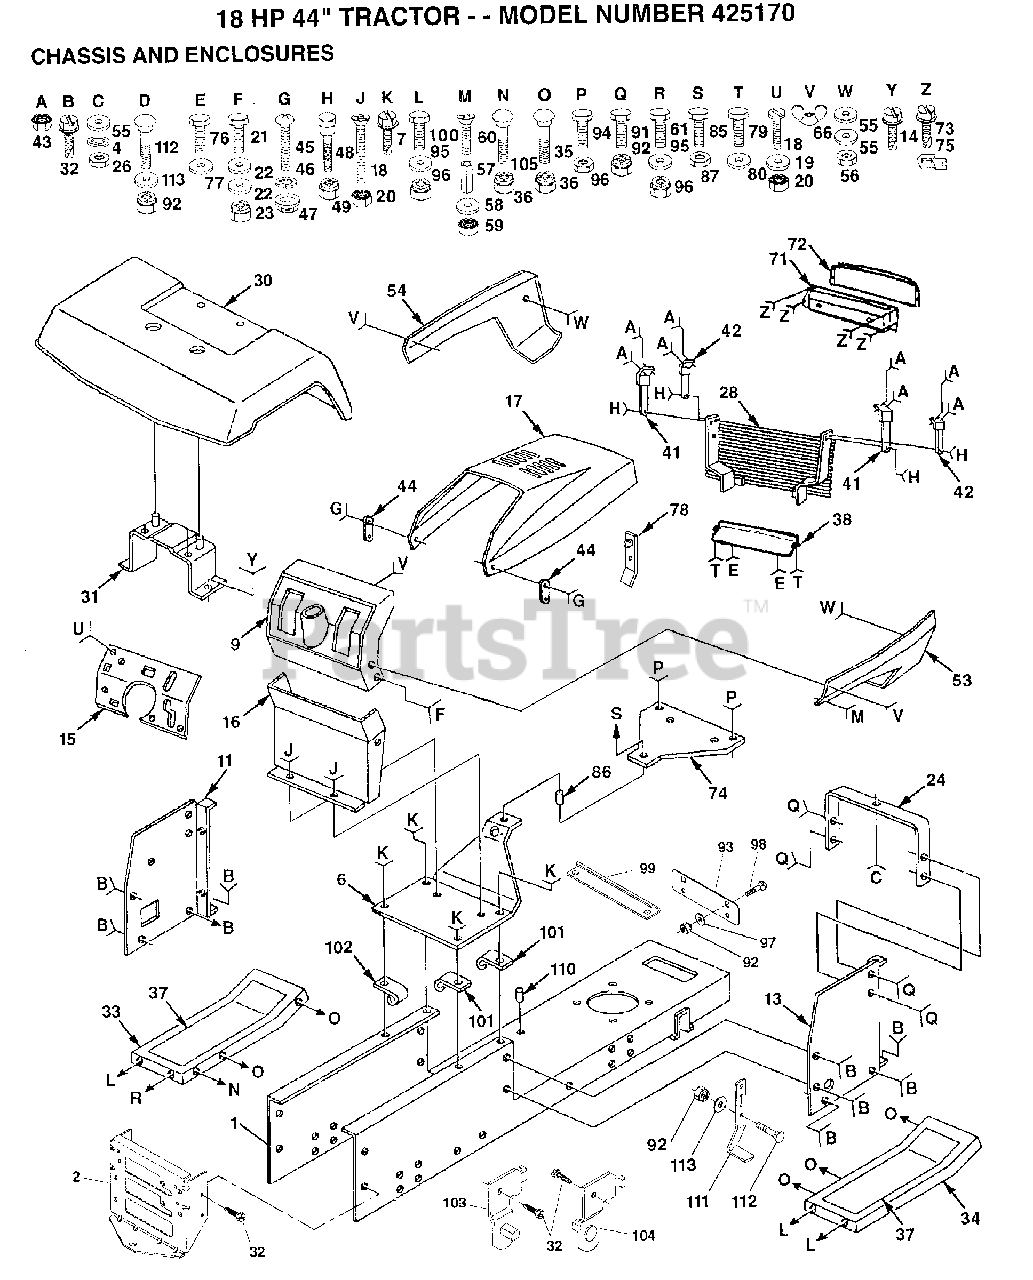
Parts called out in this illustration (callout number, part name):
4	LOCKWASHER
7	SCREW GTV
9	DASHBOARD BLACK
11	PANEL.DASH.LH.ASM
13	PANEL.DASH.RH.ASM
14	SCREW
18	SCREW
19	WASHER
22	WASHER
24	SUPPORT ASS'Y
31	BRACKET SUPT FEND
32	SCREW
35	BOLT
37	FOOTREST PAD
43	NUT
44	HOOD LATCH T
45	SCREW
46	LOCKWASHER
47	WELDNUT
55	WASHER PM
57	SPACER LT
58	WASHER
60	SCREW
72	LENS LT
74	PLATE.SUPT.BATTER
75	"""J"" FASTENER LT"
76	SCREW
77	WASHER
80	WASHER
85	BOLT
86	SPACER
87	NUT
91	BOLT
93	PLATE EXTEN FEND
94	BOLT
95	WASHER
97	WASHER
98	BOLT D
99	SPACER FENDER LT
101	CLIP T
102	"CLIP,INSULATOR"
103	BRACKET ASM LH
104	BRACKET ASM RH
111	STOP.OVER.CENTER
112	BOLT
113	WASHER GT
